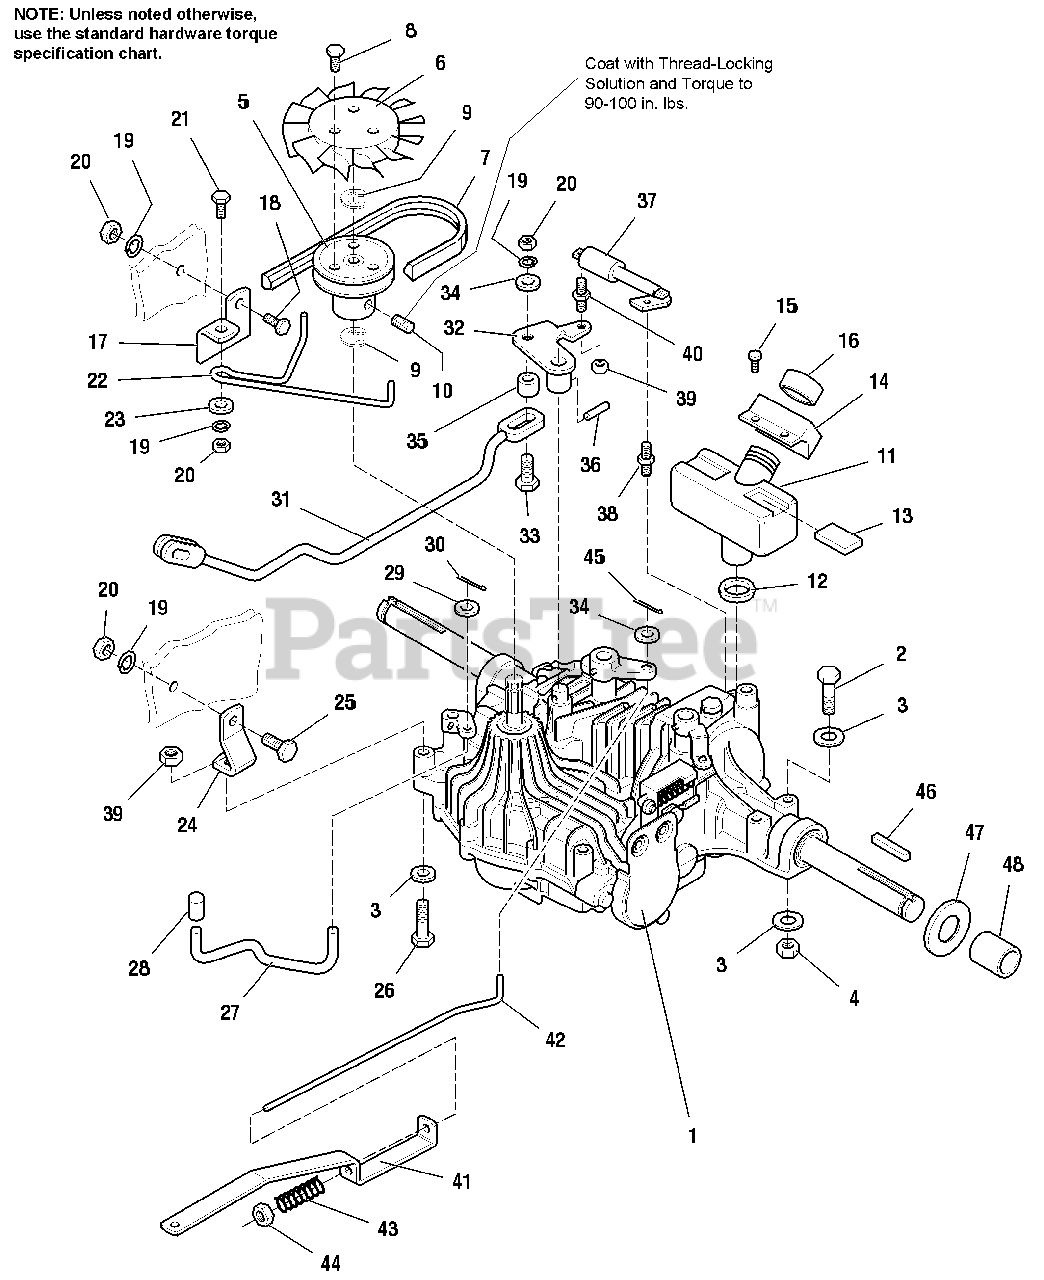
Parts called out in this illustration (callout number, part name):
1	TRANSMISSION, Tuff Torq K61
2	CAPSCREW, 5/16-18 x 3
3	WASHER, 5/16
4	NUT, Hex Lock, 5/16-18
5	PULLEY & HUB ASSY
8	CAPSCREW, Taptite, 1/4-20 x 1-1/8
9	RETAINING RING, #55
10	SET SCREW, Hex, 5/16-18 x 5/16
11	TANK, Expansion Chamber
15	FASTENER, Panel
16	CAP, Filler
17	BRACKET, Belt Stop
18	CAPSCREW, Hex Hd, 5/16-18 x 1
19	LOCKWASHER, 5/16
20	NUT, Hex, 5/16-18
21	CAPSCREW, Hex Hd, 5/16-18 x 1
23	WASHER, Flat, 5/16
24	BRACKET, Torque
25	CAPSCREW, Hex Flange Hd, Whizlock, 5/16-18 x 3/4
26	CAPSCREW, 5/16-18 x 2-1/2
27	ROD, Hydro Bypass
28	COVER, Wire
29	WASHER, Plain, 1/4
30	COTTER PIN, 1/16 x 3/4
31	ROD, Control
32	CONTROL ARM & HUB ASSY
33	CAPSCREW, Hex Hd, 5/16-18 x 1-1/4
34	WASHER, 5/16
35	SPACER, 21/64 x 9/16 x 5/16
37	SHOCK ABSORBER
39	NUT, Hex Flange Lock, 5/16-18, 2-Way Lock
40	STUD, 5/16-18 x 57/64
41	GUIDE, Brake Rod
43	SPRING, Compression
44	NUT, Hex Nylon Lock, 5/16-18
45	COTTER PIN
46	KEY, 1/4 x 2
48	SPACER, 1-1/64 x 1-3/64 x 1-1/2
